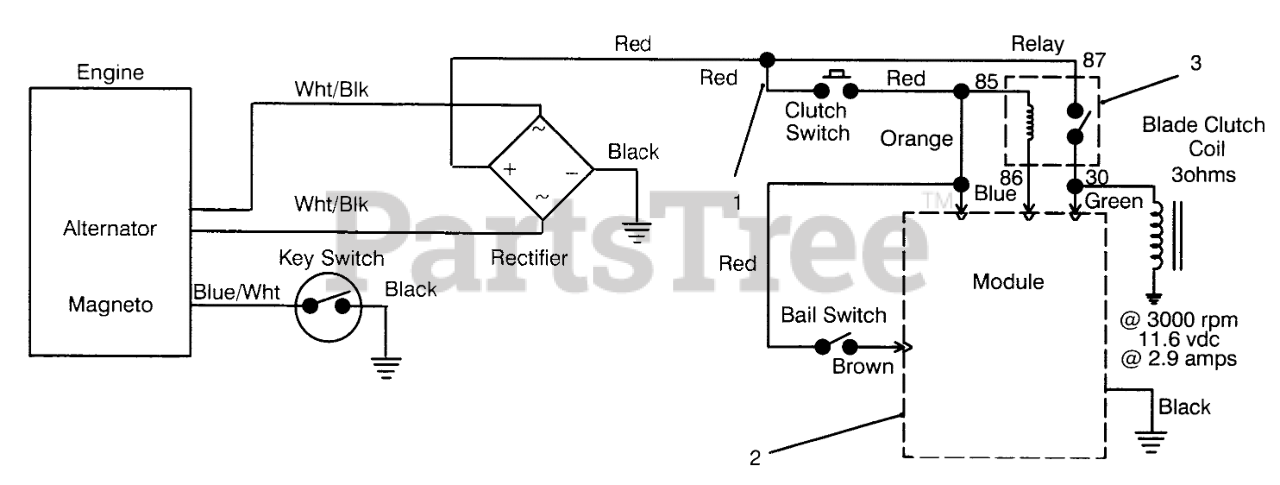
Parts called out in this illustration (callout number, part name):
1	Wire Harness
2	Module
3	RELAY
